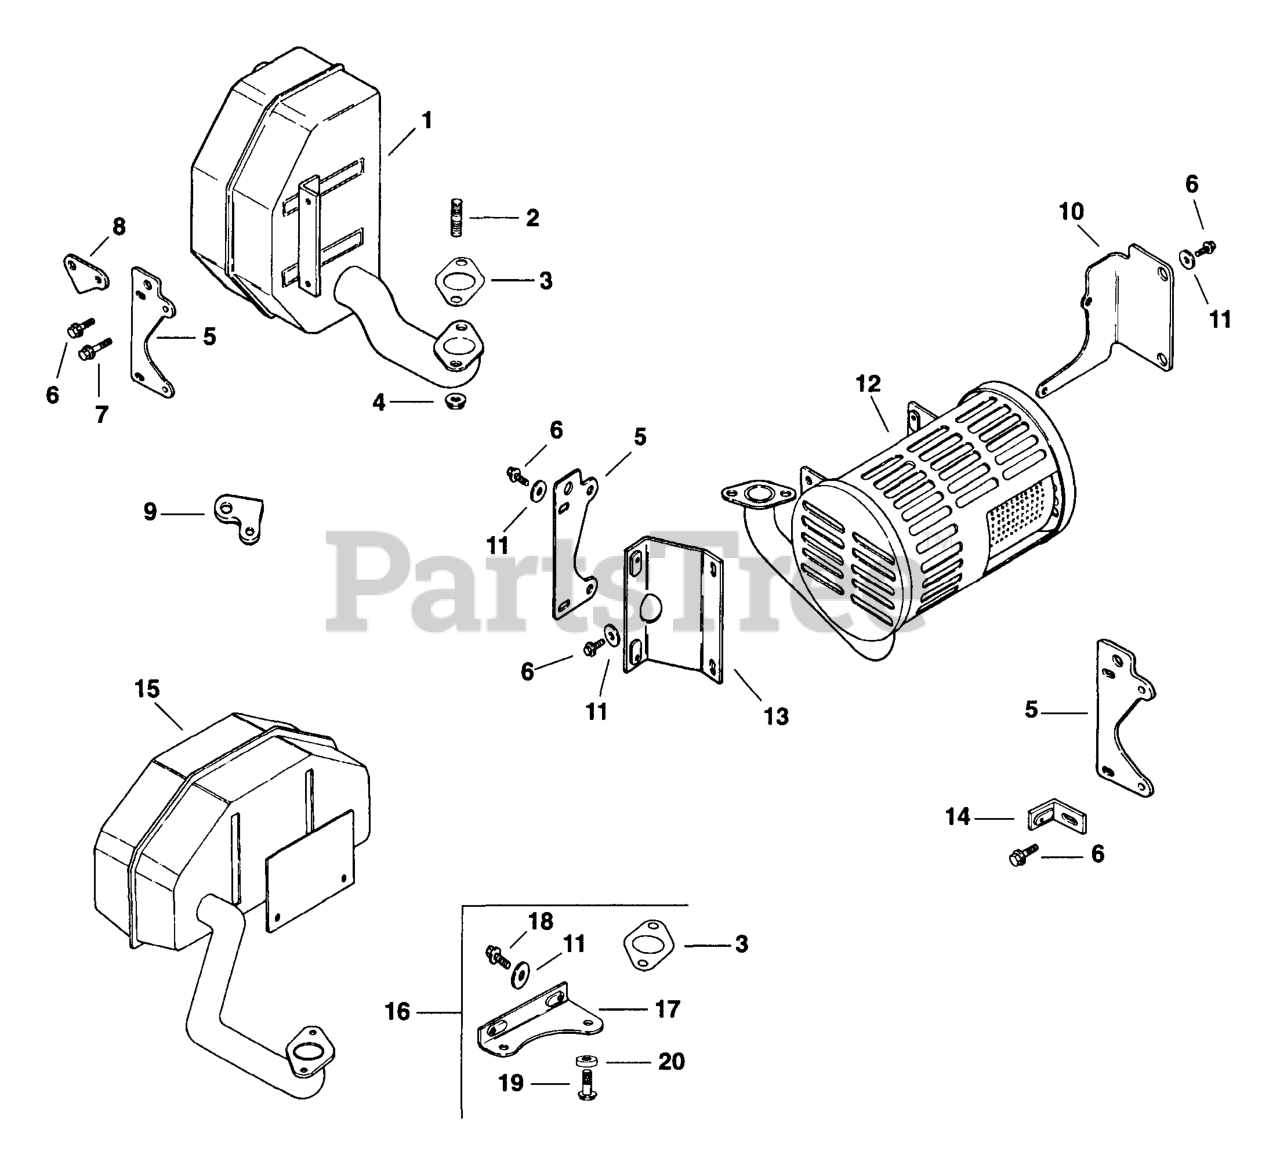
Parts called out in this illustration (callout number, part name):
2	Stud, M8x1.25x33
3	Gasket, Exhaust Manifold
4	Nut, Hex. Flange M8x1.25
5	Bracket, Muffler
7	Screw, Hex. Flange M6x1.0x25
11	Washer, Plain 1/4"
